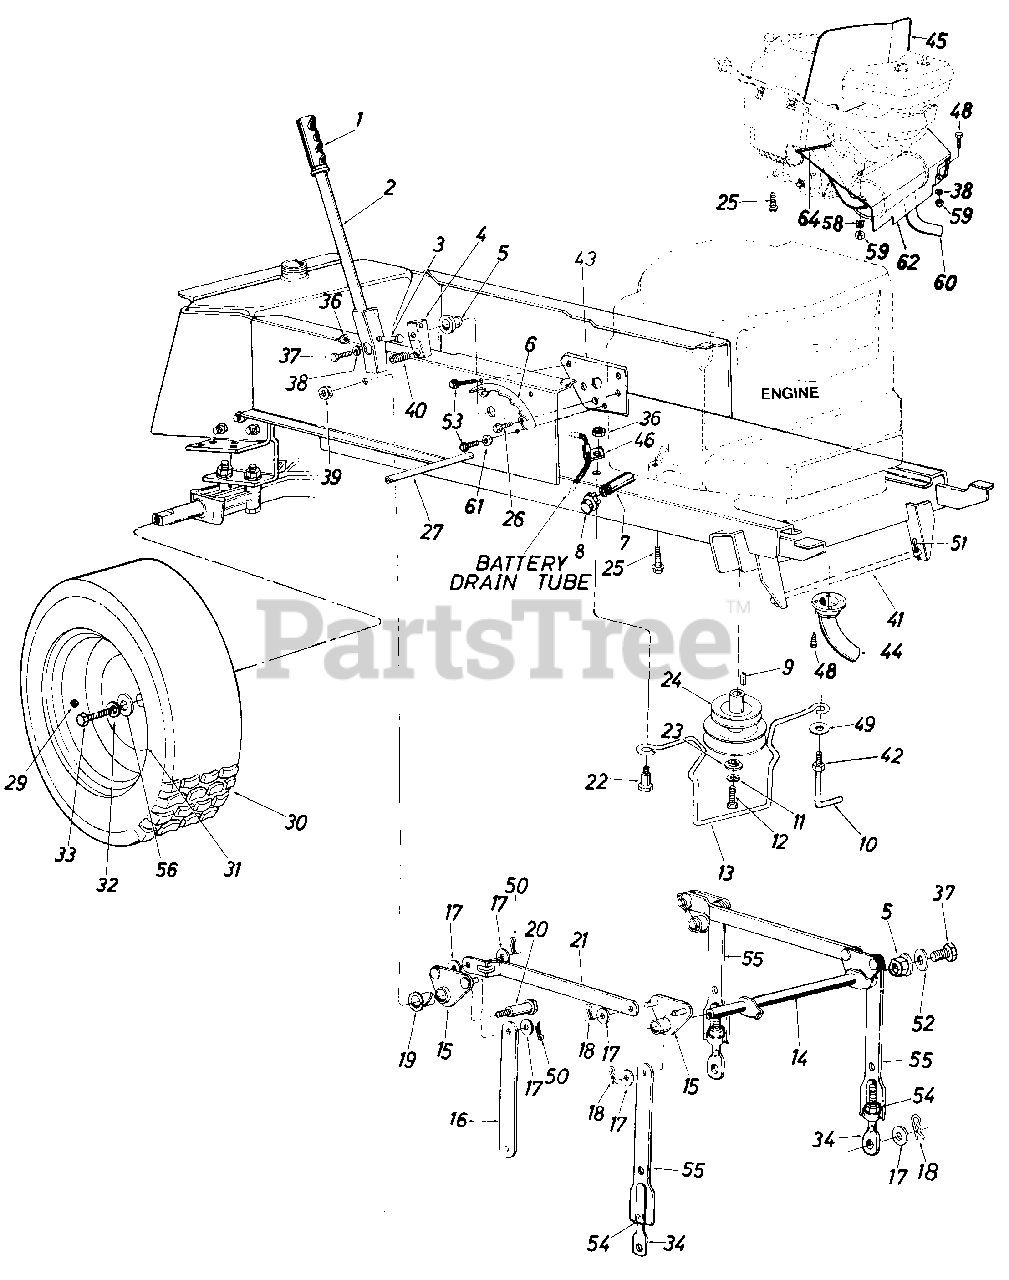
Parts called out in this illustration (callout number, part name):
1	Grip
2	Lift Handle Ass'y.
3	Hex Scr. 5/16-18 x 1.50" Lg.
4	Lift Shaft Drive
5	Plastic Hex Brg. 5/8" I.D.
8	Pipe Cap 3/8-18 Npt.
9	Sq. Key 1/4" x 1.50"
10	Belt Guard Lock Pin
11	L-Wash. 7/16" Scr.
12	Hex Scr. 7/16-20 x 1.50" Lg.
14	Lift Shaft Ass'y.
15	Lift Pivot Brkt. Ass'y.
17	Fl-Wash. 1/2" I.D. x 1.00" O.D. x .090
18	Hairpin Cotter
19	Nyliner 518" I.D. x .88" Lg.
20	Shld. Scr. 5/8" Dia. x .96" Lg. 3/8-16
23	Flat Wash. .44" I.D. x 1.25" O.D. x .17
24	Two-Step Engine Pulley
25	Hex Wash. Hd. Scr. 3/8-16 x 1.25" Lg.
26	Hex Thd. Rolling Scr. 5/16-18 x .75" Lg.
27	Running Board Rod
29	Air Valve
30	Rear Wheel Ass'y. Comp.
31	Rear Wheel Rim Only
32	Bell-Wash. .345" I.D. x .88"
33	Hex Bolt 5/16-24 x .75" Lg.
34	Eye Bolt Adj. Link 1/2-13 Thd.
36	Hex Cent. L-Nut 5/16-18 Thd.
37	Hex Scr. 5/16-24 x .62" Lg.
38	L-Wash. 5/16" I.D.
39	Hex Center L-Jam Nut 3/8-16 Thd.
40	Compression Spring
41	Deck Connecting Rod
42	Hex Nut 5/16-24 Thd.
45	Heat Shield
46	Mounting Clamp
48	Hex Bolt 5/16-18 x .75" Lg.
49	Bell-Wash. .39" I.D.
50	Cotter Pin .09 Dia. x 1.0" Lg.
51	Int. Cotter Pin
52	Flat Wash. .34" I.D. x 1.12" O.D. x .125
53	Hex Wash. Hd. AB-Tap Scr. 5/16-24 x .5" Lg.
54	Hex Nut 1/2-13 Thd.
56	Fl-Wash. .34" I.D. x 2 0n O.D.
58	Spec. L-Wash. 5116" I.D.
59	Hex Nut 5/16-18 Thd.
61	Flat Wash. .344" I.D.
62	Front Heat Shield
64	Trim Strip 10" Lg.
